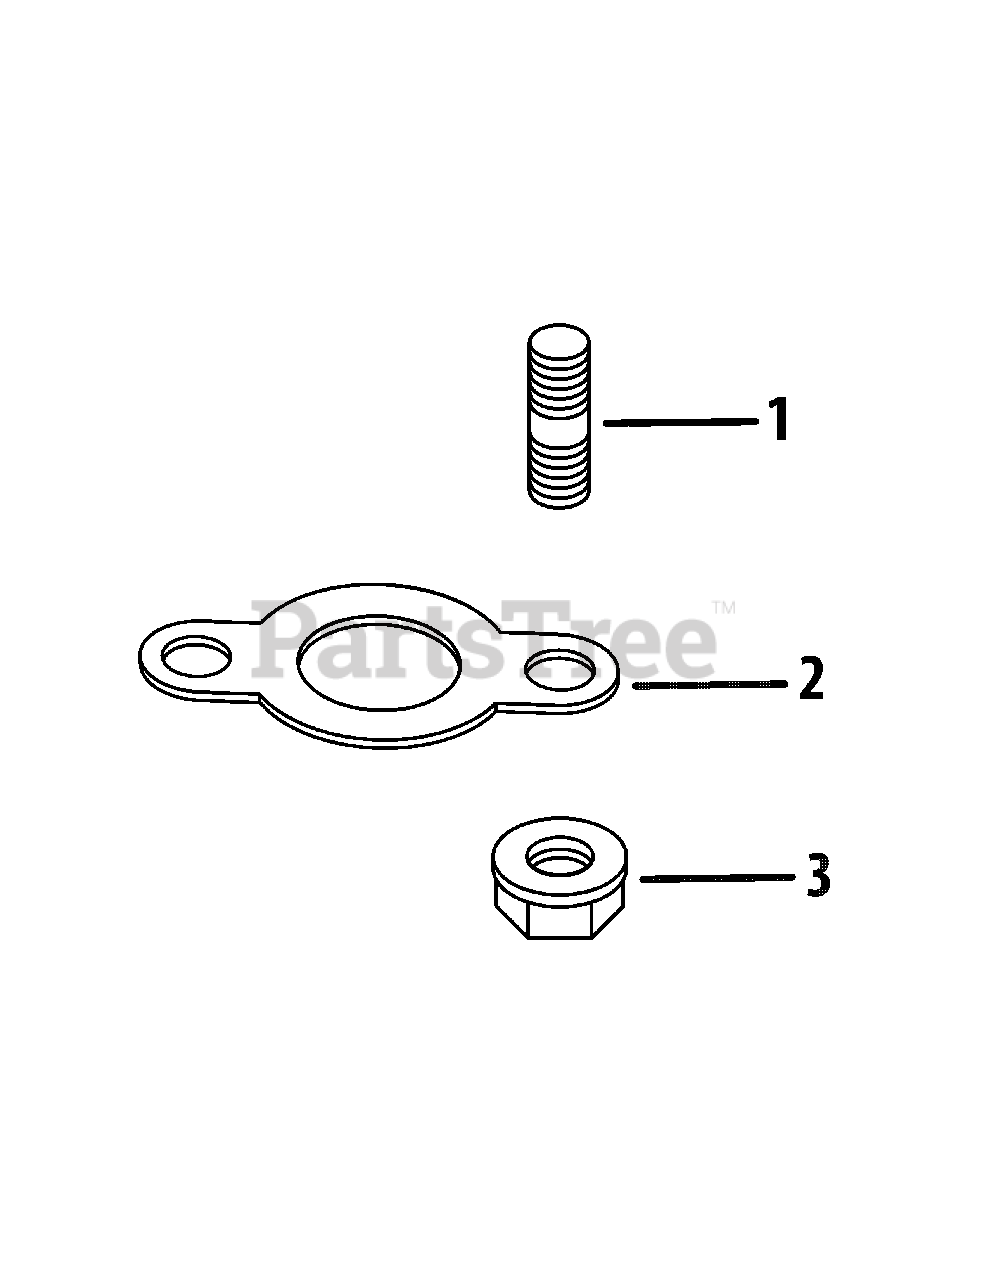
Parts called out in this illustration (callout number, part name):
1	Stud, M8X1.25X33
2	Gasket, Exhaust
3	Nut, Flg M8X1.25
